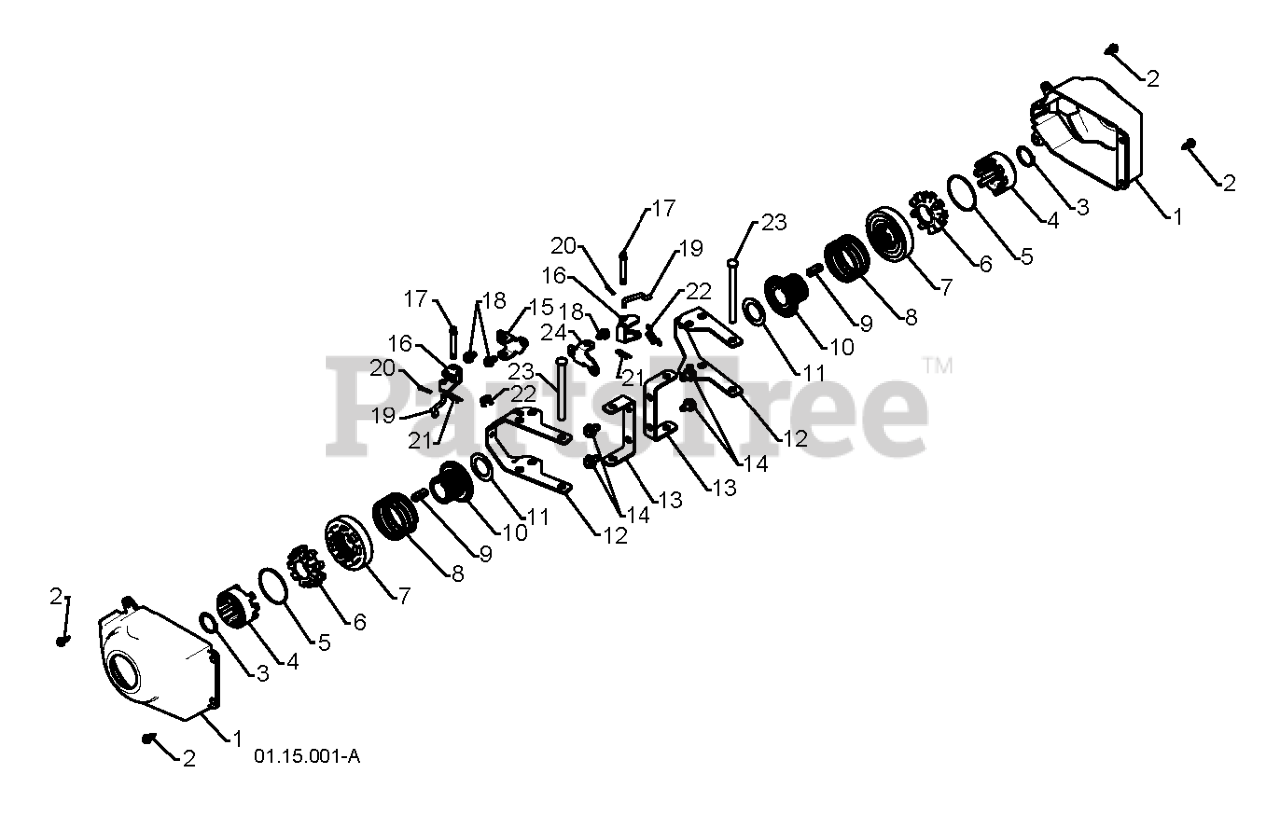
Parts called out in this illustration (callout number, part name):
1	COVER, POWER STEERING
2	SCREW, HEX HEAD, TAPPING
4	RP.DRIVER WHEEL
5	RING, WIRE RETAINER
6	LOBE WHEEL
7	RP.SLIDE.CLUTCH
8	SPRING, CLUTCH SLIDE
9	KEY, SQUARE 1/4 X .875
10	RP.LOBE.AXLE
11	WASHER TRUST 1"
12	YOKE, STEERING
13	BRACKET.STEER.PNT.BLACK
14	Screw 5/16-18 x 1/2 Hex, Self Tapping 5/16-18 x 1/2
15	BRKT.STEER.PIVOT.RH
16	BELLCRANK.STEER
17	PIN, STEERING BELLCRANK
18	SCREW 1/4X20
19	LINK.STEER.YOKE
20	RETAINER CLIP
21	RETAINER CLIP PM
22	SPRING LATCH
23	PIN, STEERING LEVER
24	BRACKET.STEER.PIVOT.LH.YZ
